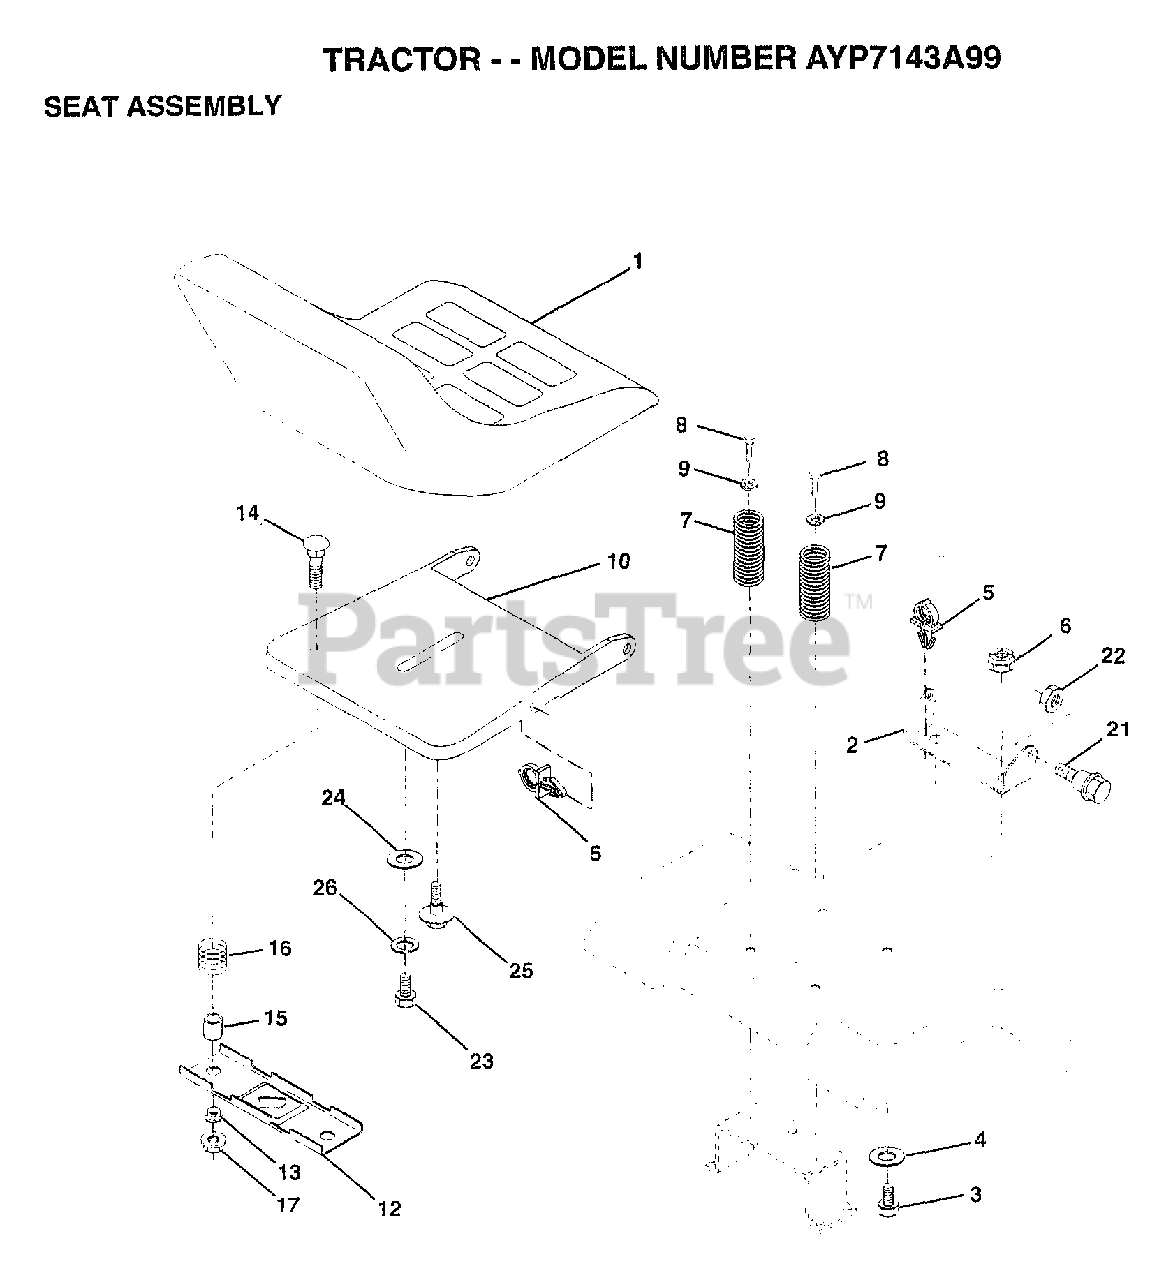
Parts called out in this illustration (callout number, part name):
2	BRACKET PVT SEAT
3	BOLT
4	WASHER PM
5	CLIP.PUSH-IN.HING
6	NUT
7	SPRING COMPRESSIO
8	SCREW GTV
9	WASHER
10	PAN-SEAT
12	BRKT SWITCH
13	BUSHING
14	BOLT-RD HD SQ NK
15	SPLIT SPACER
16	SPRING
21	"BOLT,SHOULDER"
22	NUT
23	BOLT
24	WASHER
25	"BOLT,SHOULDER"
26	LOCKWASHER
